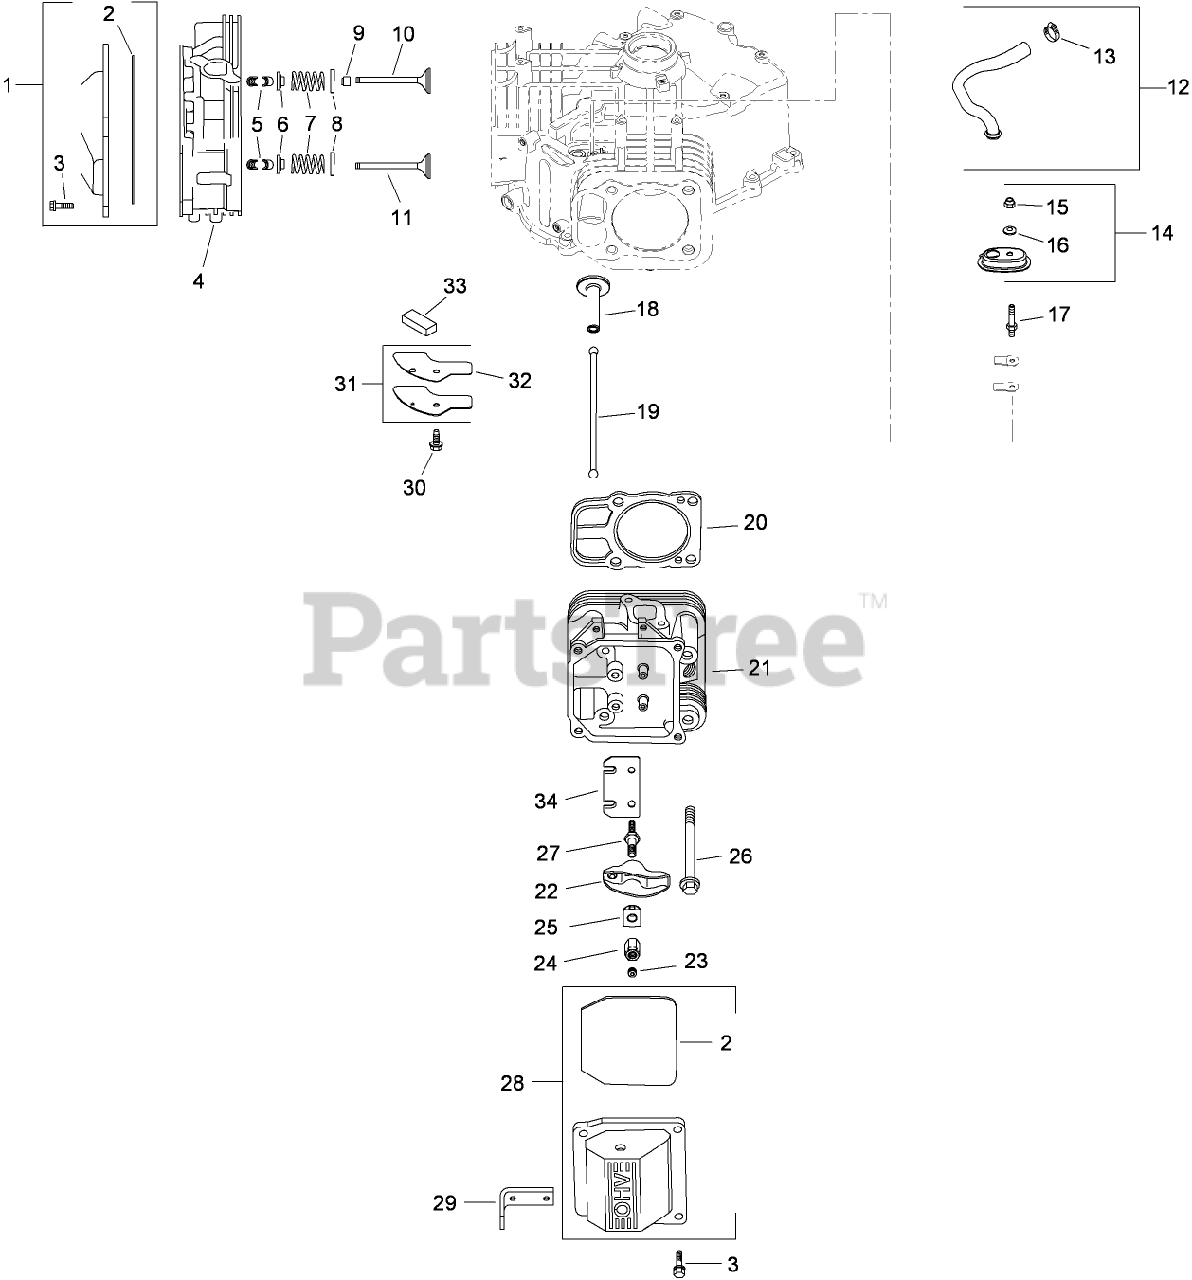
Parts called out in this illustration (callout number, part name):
1	PLAIN ROCKER COVER KIT
2	O-RING
3	SCREW-FLANGE (M6X1.0X30)
4	No.1 CYLINDER HEAD KIT ASM
5	RETAINER KIT
6	CAP-SPRING, VALVE
7	SPRING-VALVE
8	RETAINER-SPRING
9	SEAL-STEM, VALVE
10	VALVE-INTAKE (STD)
11	VALVE-EXHAUST (STD)
12	BREATHER HOSE KIT
13	CLAMP-HOSE, SPRING (1/2)
14	BREATHER HOUSING KIT (INCLUDES 15-16)
15	NUT-LOCK (M5X.8)
16	WASHER-SEALING
17	STUD-COVER, BREATHER
18	Tappet
19	ROD-PUSH
20	CYLINDER HEAD GASKET KIT
21	CYLINDER No.2 HEAD ASM
22	ARM-ROCKER
23	NUT (M10X0.75 )
24	SCREW-SET
25	PIVOT-ARM, ROCKER
26	SCREW-FLANGE (M10X1.5X90)
27	STUD-ROCKER
28	BREATHER VALVE COVER KIT
29	STRAP-LIFTING
30	SCREW-FLANGE, THREAD FORMING (M6X1.0X16)
31	BREATHER COVER KIT
32	GASKET-COVER, BREATHER
33	FILTER-BREATHER
34	PLATE-GUIDE
